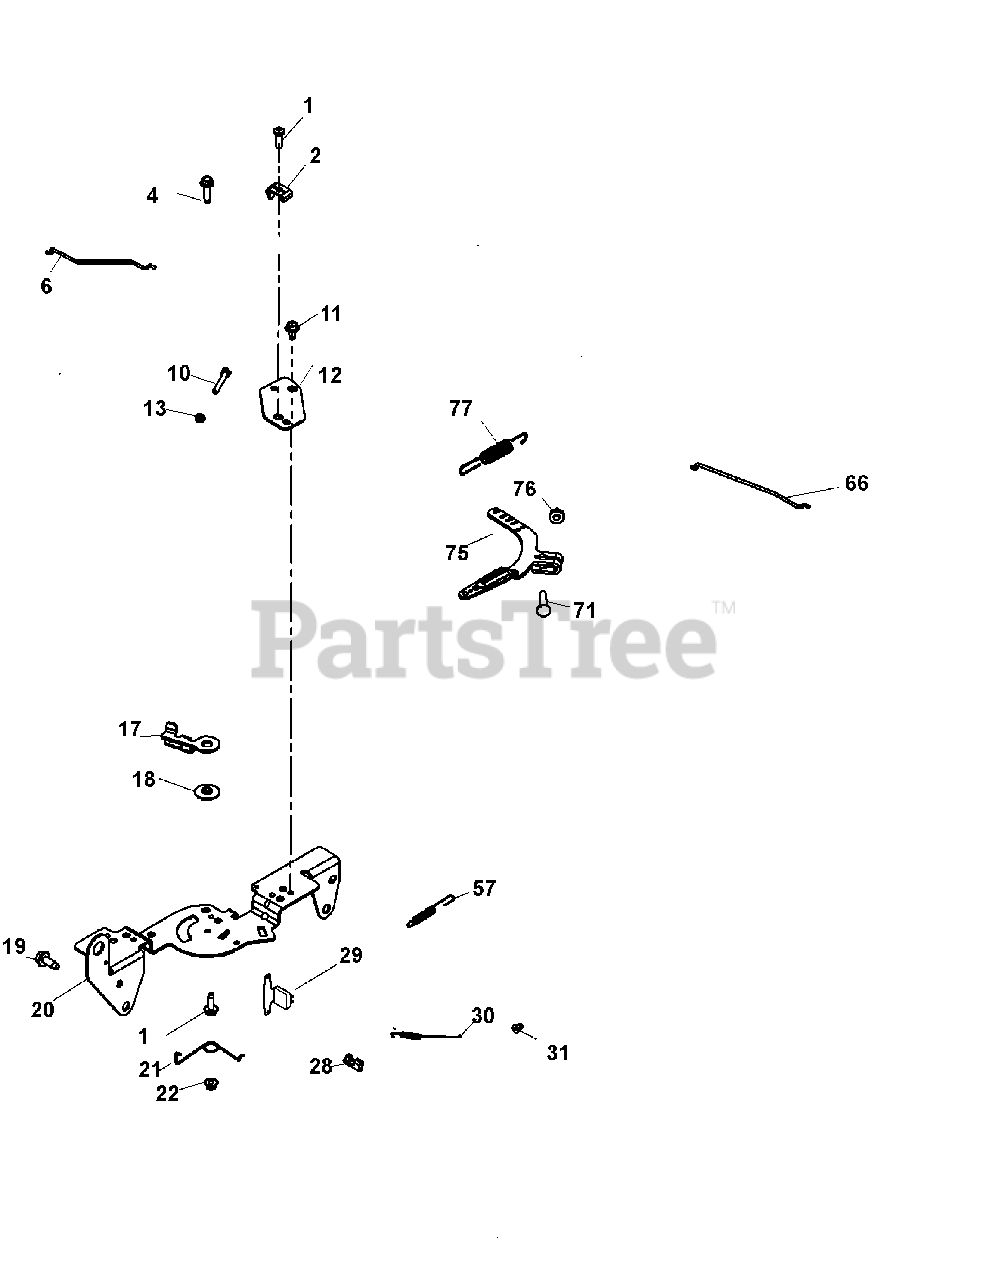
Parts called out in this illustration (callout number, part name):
1	Screw, Thread Forming
2	Clamp, Cable
4	Screw, Thread Forming
6	Linkage, Choke
10	Screw, Cap M4X.7X30
17	Lever, Throttle Actuator
18	Spacer, Control Assy
19	Screw, Thread Forming
20	Bracket, Control
21	Spring, Choke Return
22	Nut, Lock M5X.8
28	Bushing, Throttle Linkage
30	Spring, Linkage
31	Bushing, Linkage Retaining
57	Spring, Throttle Limiter
66	Linkage, Throttle
71	Bolt, Rd Hd Sq Neck M6X1.0X25
75	Lever, Governor
76	Nut, Flg M6X1.0
77	Spring, Governor (Purple)
